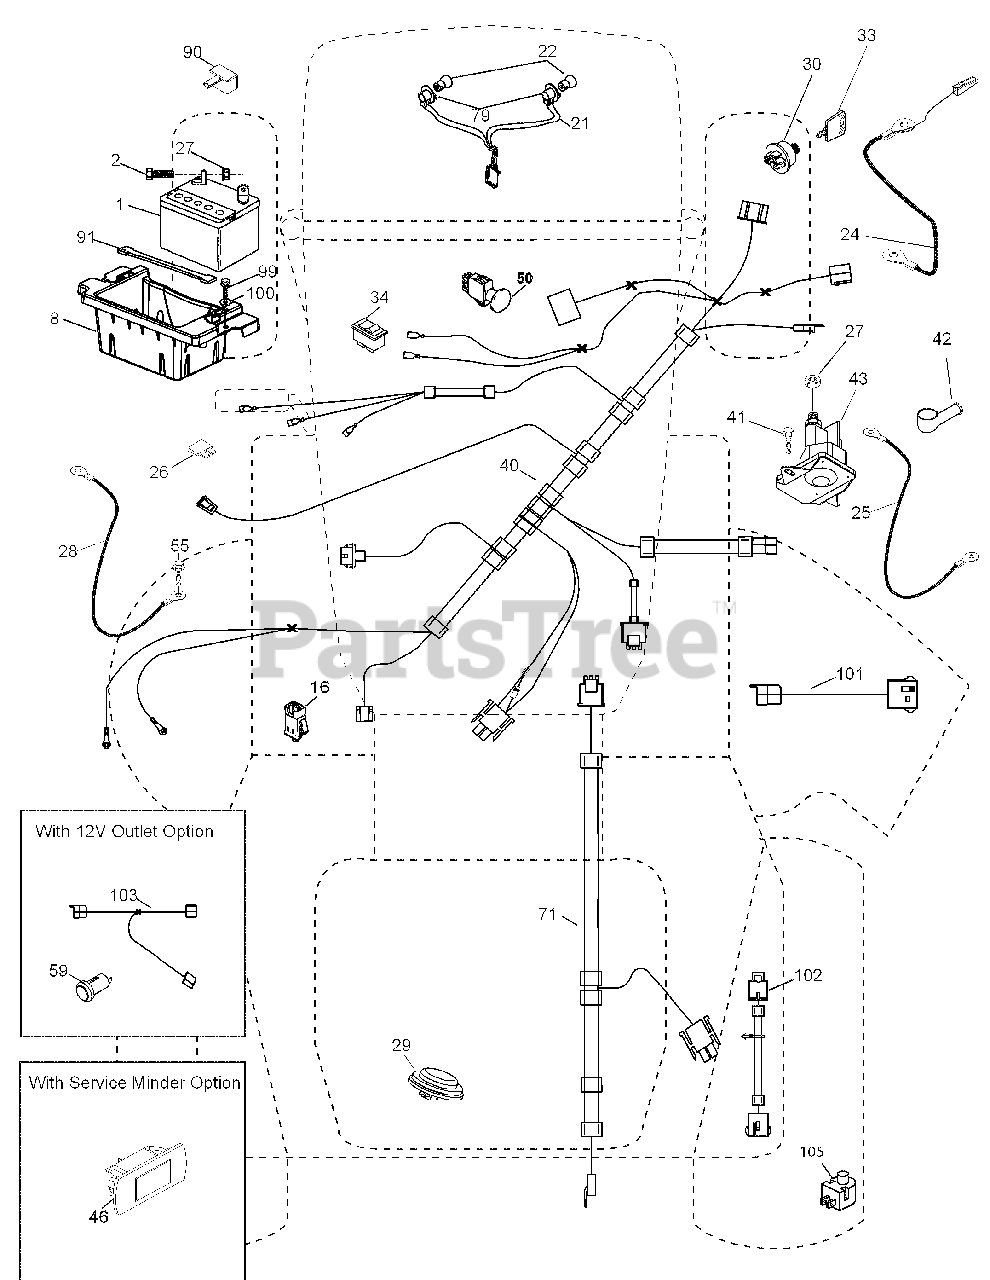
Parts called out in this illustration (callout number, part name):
1	Battery
2	Bolt Hex Head 1/4-20 x 3/4
8	Box Battery
16	Switch Interlock Push-In
21	Harness Socket Light W/4152J
22	Bulb Light
24	Cable Battery
25	Cable Starter
27	Nut Keps Hex 1/4-20 unc
28	Cable, Ground
29	Switch, Seat
30	Switch, Ign
34	Switch Light / Reset
40	Harness Ign. Dash
41	Screw Thd Cut 1/4-20 x 1/2
42	Cover, Terminal
43	Solenoid
46	Gauge Servicereminder Hrmtr
50	Switch PTO
55	Screw Thdrol 5/16-18 x 3/4 TYTT
59	Outlet 12-Volt
71	Harness Ign.
79	Socket Asm Bulb Twistlock
81	Relay Harness Sealed
90	Cover Terminal
91	Strap Battery Mount
99	Screw Hexwsh Thdrol 1/4-20 x 3/4
100	Washer 9/32 x 7/8 x 16 Ga.
101	Harness Pigtail
102	Harness Pigtail
103	Harness 12-Volt Pigtail
105	Switch Reverse TT Pedal Control
